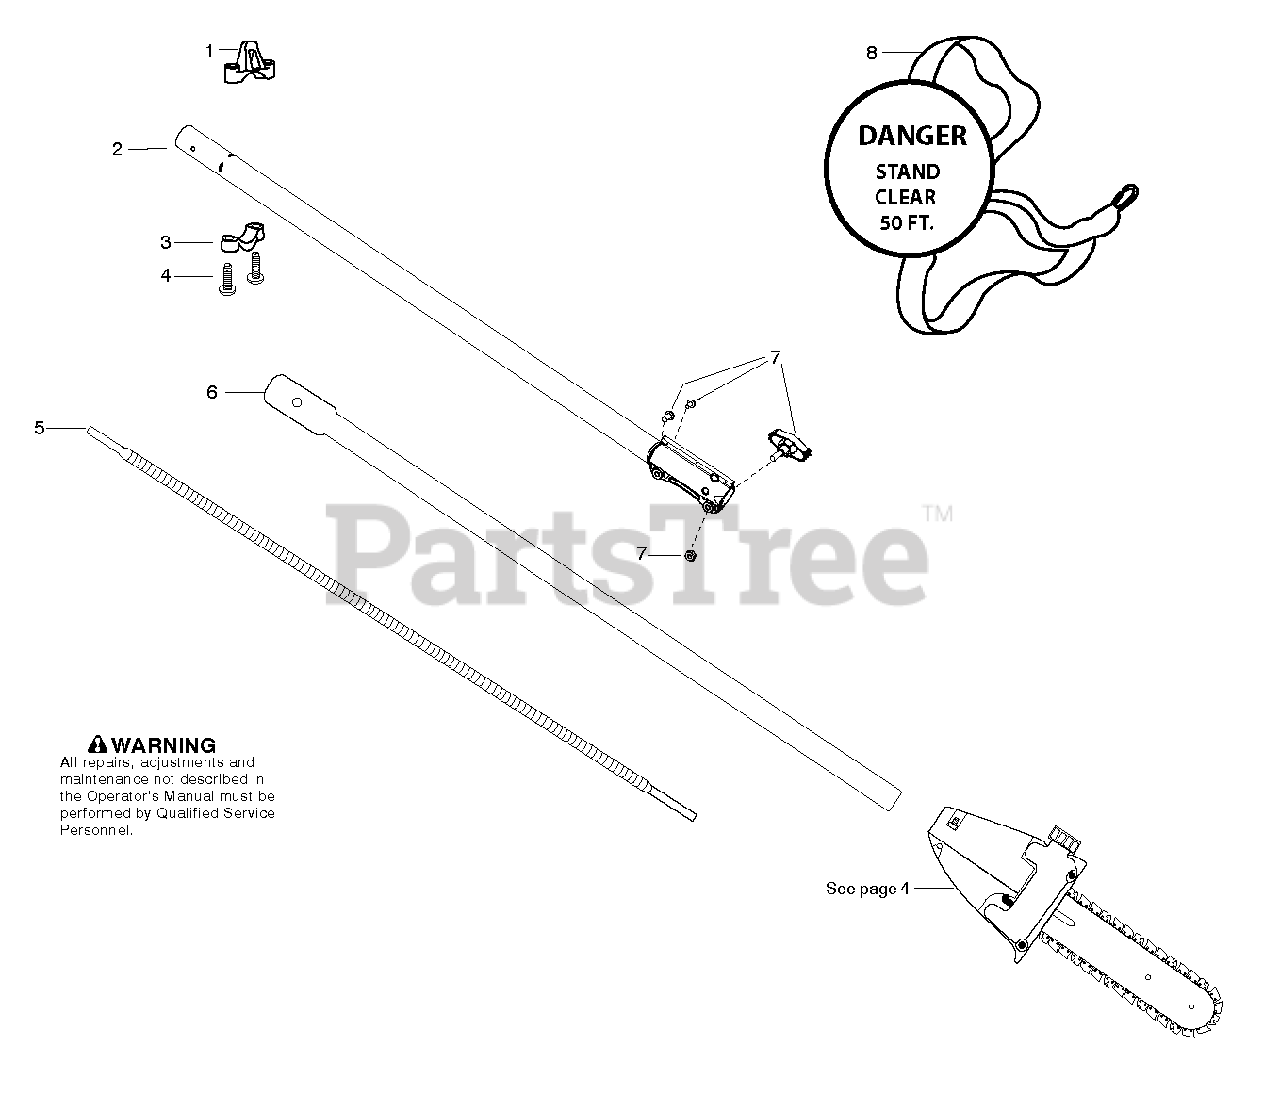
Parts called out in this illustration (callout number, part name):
1	CLAMP HARNESS UPPER
2	TUBE
3	CLAMP LOWER HARNESS
5	FLEX-LOWER
6	ASSY D'SHAFT SVC 24" BLACK
7	ASSY COUPLER BLACK
8	ASSY,SHOULDER STRAP
